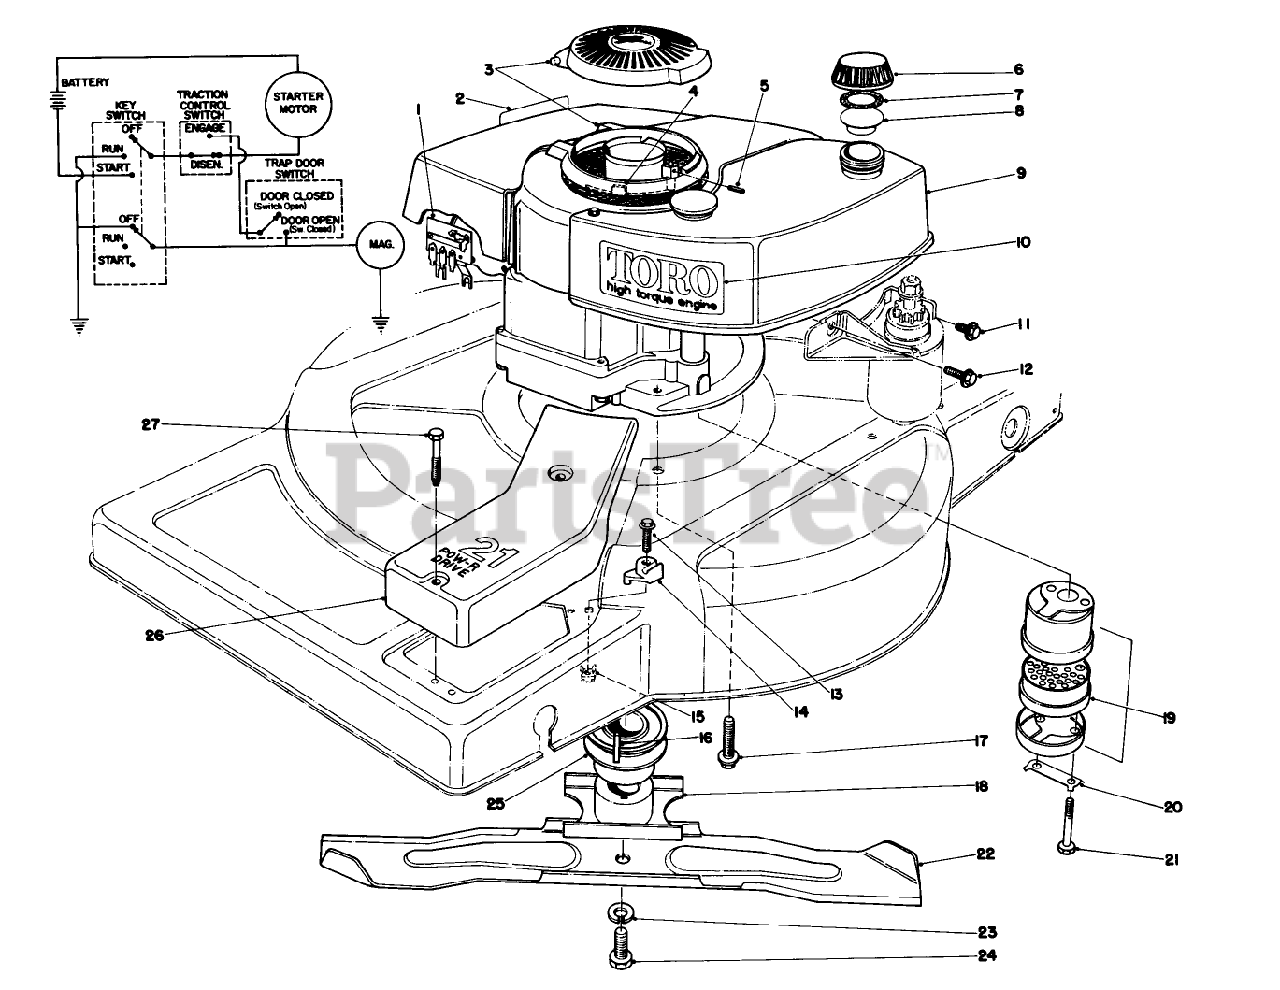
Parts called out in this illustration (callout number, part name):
1	SWITCH & TERM BLK CVR
2	Decal-Maintenan
3	Cover Assembly
4	WIRE CLIP
5	SPRING PIN
6	Gas Cap (Incl. Ref. #7 & 8)
7	GASKET
8	GAS CAP BAFFLE
9	Engine
10	High Torque
11	SCREW
12	Screw
14	CABLE BOSS
15	SPEED NUT
16	KEY-SQUARE
17	SCREW-HWHTF
18	BLADE RETAINER WA(BLACK)
19	Muffler Assembly (Incl. Ref. #20 & 21)
20	CLIP - LOCKING
21	SCREW-HH
22	Blade
23	WASHER-LOCK
24	BLADE SCREW
25	Pulley
26	COVER BELT
27	SCREW-HHFTF
